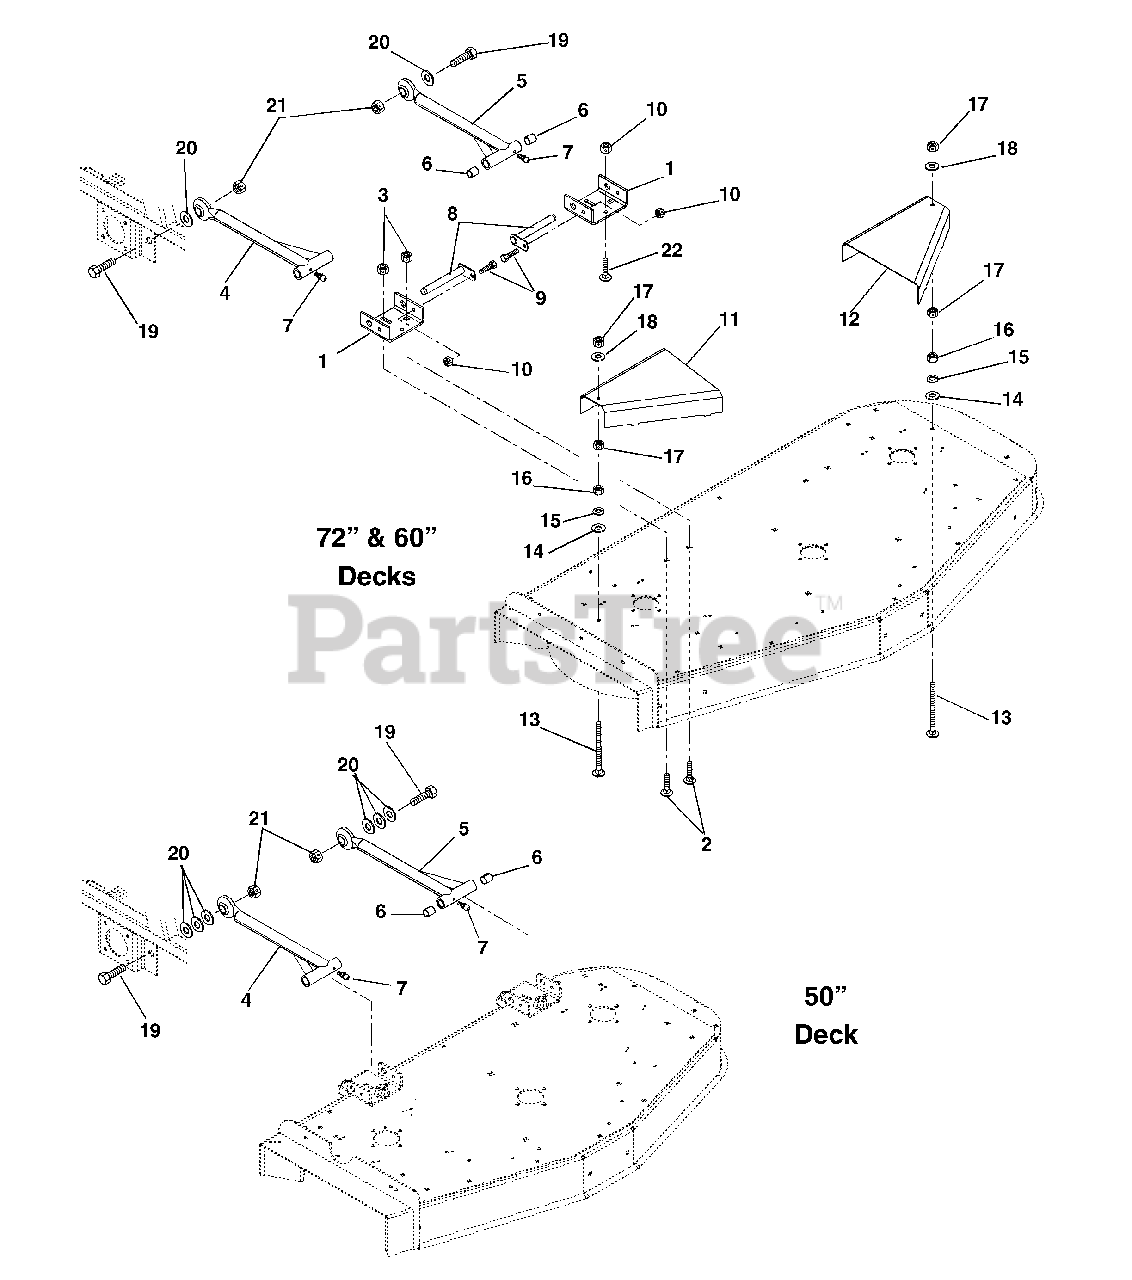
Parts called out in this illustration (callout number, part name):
1	Bracket, Mower Mounting (Rear)
2	Bolt-Round Head Square Neck .50-13 x 1.00 Grade 2
3	Nut-Locking-Center .50-13
4	Assembly, Mower Mounting Arm
5	Weldment-Mower Mounting Arm
6	Bearing .75 x .875 x 1.00
7	Fitting-Lube .25-28 x .256
8	Weldment, Mower Mounting Pin
9	Bolt-Hex .38-16 x .75 Grade 5
10	Nut-Locking-Center .38-16
11	Guard, Pulley Right Hand
12	Guard, Pulley Left Hand
13	Bolt-Round Head Square Neck .31-18 x 3.50
14	Washer-Flat-Steel .344 x .688 x .065
15	Washer-Locking .31 x .078
16	Nut-Hex .31-18
17	Nut-Locking-Center .31-18
18	Washer-Flat-Steel .438 x 1.00 x.083
19	Bolt-Hex .875-9 x 2.75 Grade 5
20	Washer-Flat-Steel .875 x 1.500 x .1196
21	Nut-Locking-Center .875-9
22	Bolt-Round Head Square Neck .38-16 x 1.00 Grade 5
